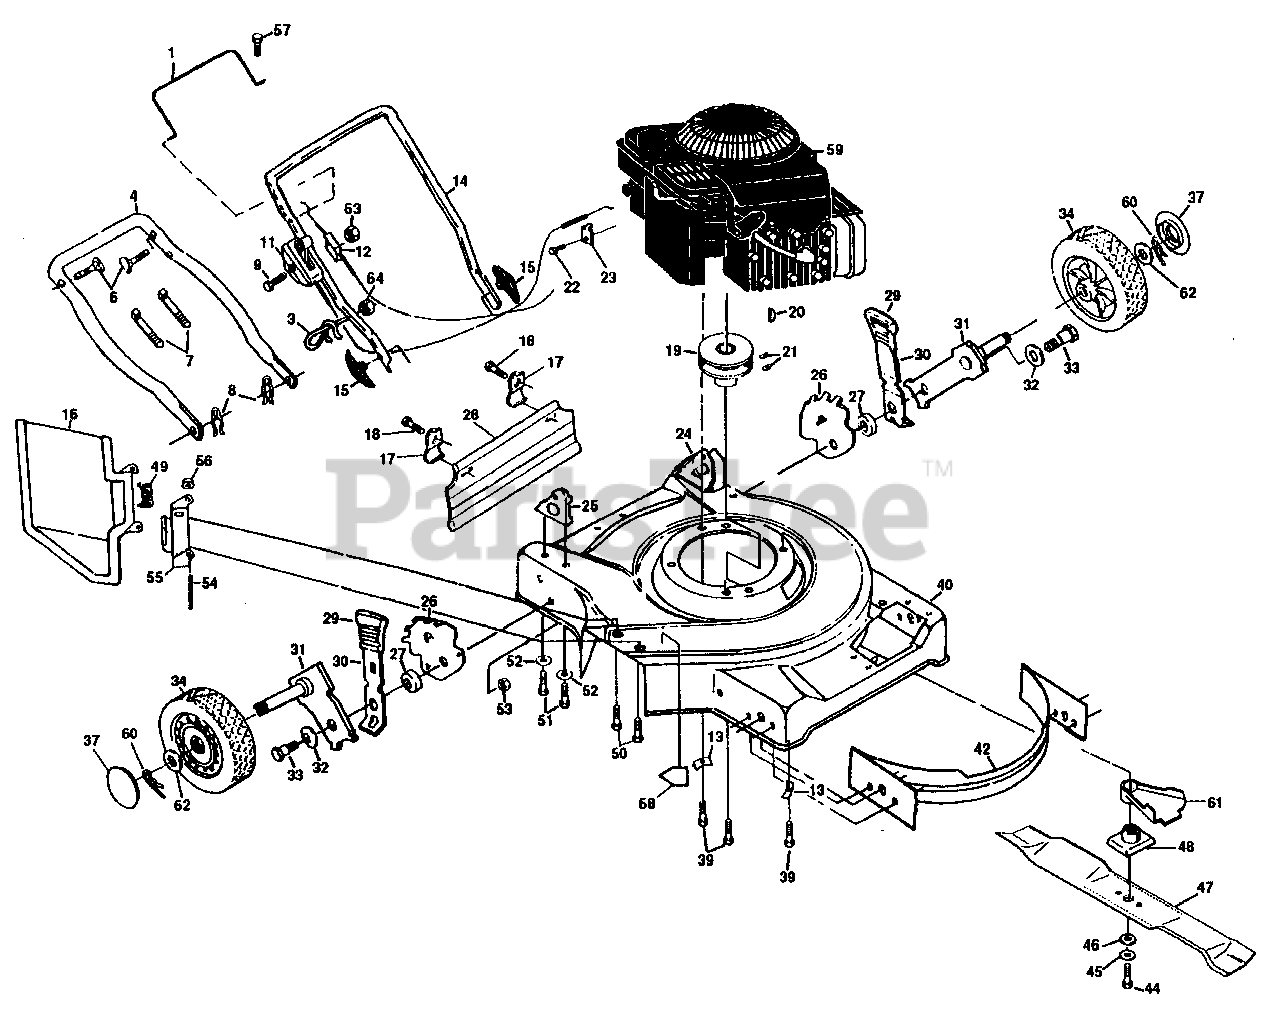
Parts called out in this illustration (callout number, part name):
1	Control Bar (AYP part number)
3	Rope Guide
4	Lower Handle (AYP part number)
6	Handle Bolt (AYP part number)
7	Wire Tie (AYP part number)
8	Hairpin Cotter (AYP part number)
9	Hex Washer Hd Screw 1/4-20 x 2-1/4 (AYP part number)
11	Deluxe Throttle Control
12	Engine Zone Control Cable
13	Engine Washer (AYP part number)
14	Upper Handle (AYP part number)
15	Handle Knob (AYP part number)
16	Discharge Guard
17	Bracket Skirt (AYP part number)
18	Screw Hex Washer Head (AYP part number)
19	Engine Pulley (AYP part number)
20	Hi Pro Key #HP-505 (AYP part number)
21	Set Screw 1/4-20 x 5/16 (AYP part number)
22	Thread Rolling Screw #10-32 x 5/8 (AYP part number)
23	Cable Clamp (Engine) (AYP part number)
24	Handle Bracket Assembly (Left) (AYP part number)
25	Handle Bracket Assembly (Right) (AYP part number)
26	Wheel Adjuster Bracket (AYP part number)
27	Spacer (AYP part number)
28	Rear Skirt (AYP part number)
29	Selector Knob
30	Selector Spring (AYP part number)
31	Axle Arm Assembly (AYP part number)
32	Belleville Washer 1/2 (AYP part number)
33	Shoulder Bolt 3/8-16 (AYP part number)
34	Wheel & Tire Assembly (Rear) (AYP part number)
37	Hubcap (AYP part number)
39	Hex Head Thread Rolling Screw 3/8-16 x 1-1/8 (AYP part number)
40	Lawn Mower Housing Kit (Inc. 58)
42	Front Baffle (AYP part number)
44	Hex Head Machine Screw 3/8-24 x 1-3/8
45	Helical Lockwasher 3/8 (AYP part number)
46	Hardened Washer (AYP part number)
47	22" Blade (AYP part number)
48	Blade Adapter
49	Torsion Spring (AYP part number)
50	Hex Head Thread Rolling Screw w/Sems 1/4-20 (AYP part number)
51	Thread Cutting Screw 5/16-18 x 3/4 (AYP part number)
52	Washer 5/16 (AYP part number)
53	Locknut 3/8-16 (AYP part number)
54	Hinge Rod (AYP part number)
55	Housing Bracket (AYP part number)
56	Push-on Speed Nut (AYP part number)
57	Self-tapping Screw #10-24 x 5/8 (AYP part number)
58	Danger Decal (Housing) (AYP part number)
60	Retainer Clip (AYP part number)
61	Shield Debris
62	Washer 17/32 x 1 x 21 Ga. (AYP part number)
63	Locknut 1/4-20 (AYP part number)
64	Locknut, Keps (AYP part number)
